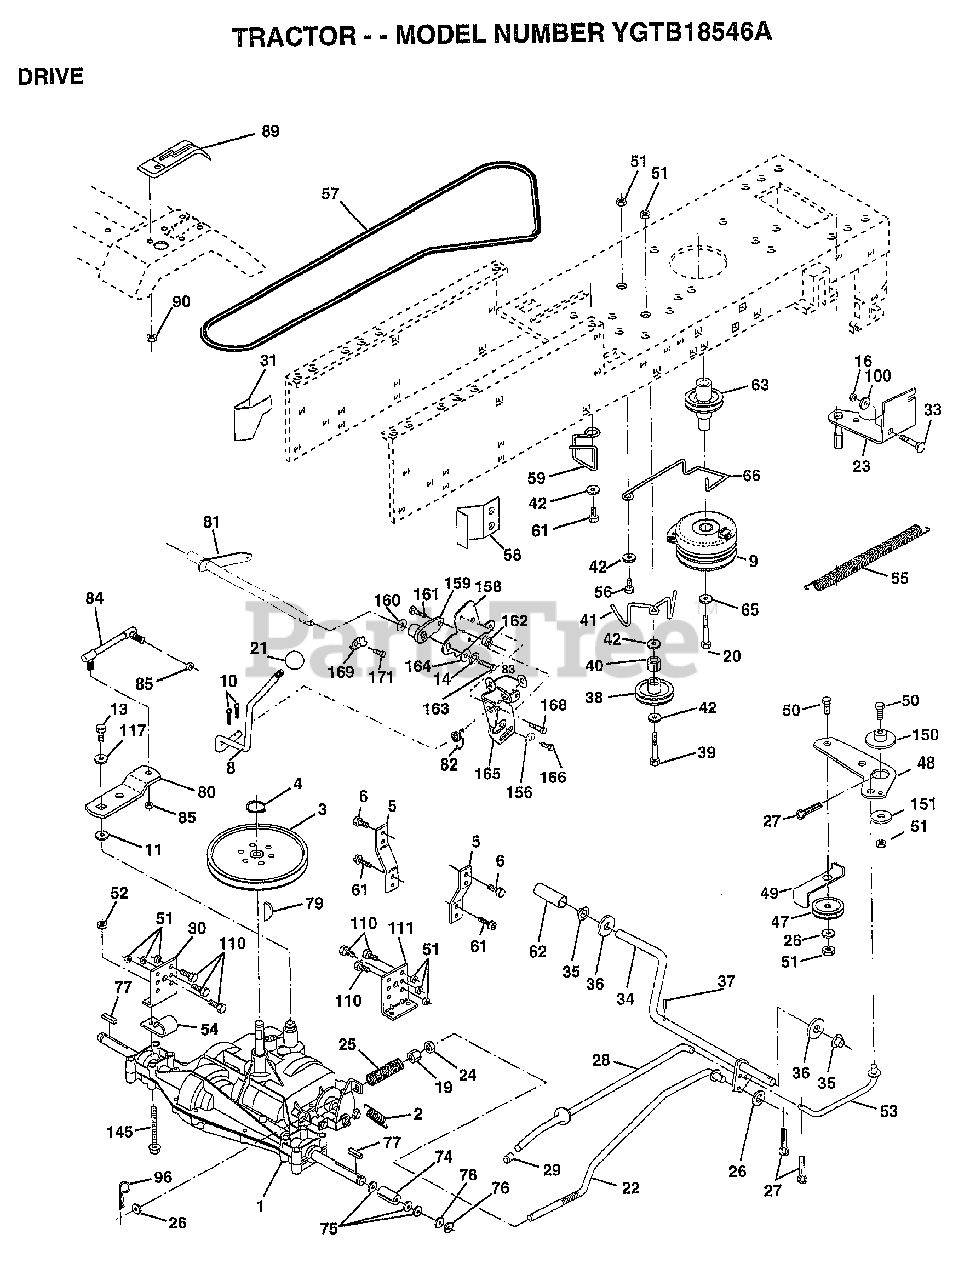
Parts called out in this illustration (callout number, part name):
3	PULLEY TRANSAXLE
4	RING
5	STRAP TORQUE
6	SCREW
8	ROD.SHIFT.FEND.ADJ.YT
9	CLUTCH.ELECTRIC
10	PIN COTTER 1/8
11	WASH-SHFT PLT LT
13	BOLT.1/4-28.W/PAT
14	LOCKWASHER
16	NUT
19	NUT
20	BOLT.7/16-20X4.25
21	KNOB.DUCKHEAD.1/2
22	ROD.ASM.BK.44.MWR
23	BRACKET.CLUT.MTG.
24	NUT
25	"SPRING,ROD BRAKE"
26	WASHER
27	COTTER PIN
28	ROD.BRAKE.PARK.LT
29	PLUNGER CAP T
30	BRKT TRANS LH
31	KEEPER BELT LH
33	BOLT
34	SHAFT ASM-PEDAL F
35	NYLON BEARING
36	WASHER LT
38	FLAT IDLER PULLEY
39	BOLT
40	SPACER T
41	"KEEPER,BELT.IDLER FLAT"
42	WASHER
48	BELLCRANK.CLUTCH
49	RETAIN BELT
53	"LINK, CLUTCH T"
54	"CLIP,INSULATOR"
55	"SPRING, RETURN LT"
57	V-BELT.DRIVE
58	"KEEPER,BELT RH"
59	KEEPER BELT CNTSP
61	SCREW
62	"COVER,PEDAL"
63	PULLEY.CLUTCH.EVX
65	LOCKWASHER
66	KEEPER-BELT
74	SPACER HYT
75	WASHER
76	E RING HYT
77	SQ KEY STD
80	"ARM,SHIFT"
81	SHAFT ASM. CROSS TAPERED
82	"SPRING,TORSION"
83	WASHER
84	LINK TRANSAXLE
85	NUT.CNT.LOCK.1/4
89	CONSOLE.SHIFT.6SP.GTV.BLACK
90	NUT
96	RETAINER M
100	WASHER M
111	BRKT TRANS RH
117	WASHER PM
145	BOLT.HEX.FLGHD
150	BUSHING.BELLCRANK.GRD.DR
151	WASHER
156	WASHER.SRRTD.5/16
158	BRKT.SHIFT.MOUNT
159	HUB.SHIFT
160	WASHER
161	BOLT T
164	WASHER.5/8X.281X10GA
165	BRKT.PIVOT.LEVER
166	SCREW.5/16-18X5/8
168	BOLT.SHOULDER.5/16-18X.561
169	PLATE.FASTENING
171	SCREW LT
